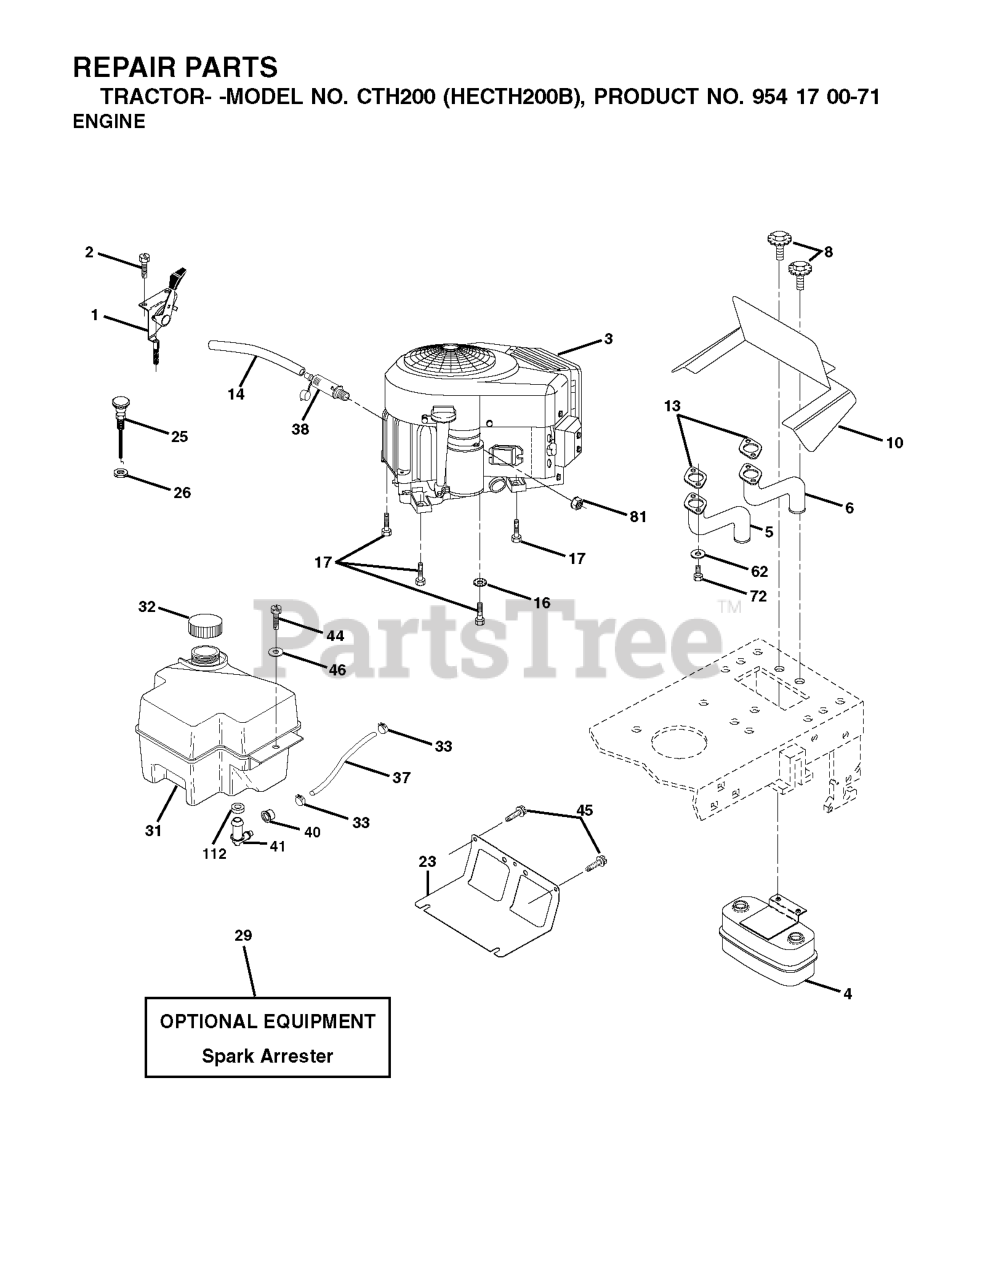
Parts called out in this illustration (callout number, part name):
1	CONTROL, THROTTLE
2	SCREW
4	MUFFLER.TWIN.CYL.LOW.TONE
5	RP.EXHAUST.TUBE.LH.BS/TWIN
6	EXHAUST.TUBE.RH.BS/TWIN
8	BOLT.5/16-18UNCX3/4 W/SEMS.BLK
10	SHIELD.BROWNING.B&S
13	GASKET.MUFFLER
14	TUBE, DRAIN OIL ASM.
16	LOCKWASHER
17	SCREW 3/8-16 X 1-1/2
23	SHIELD.BROWNING.DBR.GUARD
25	CONTROL, CHOKE
26	Nut Keps 3/8 - 24 UNF
29	KIT.SPARK ARRESTOR 794945 B&S
31	GAS TANK 2GAL
32	FUEL CAP
33	HOSE CLAMP
37	LINE.FUEL.20
38	PLUG, OIL DRAIN EASY
40	BUSHING.SNAP.NYL.BLK.
41	STEM FUEL TANK
44	SCREW HEXWSHR 1/4-20X3/4
45	SCREW, 3/8-16X3/4
62	WASHER.LOCK.HVY.HLCL.SPR.5/16
72	SCREW
81	NUT
112	BUSHING OUTLET T
